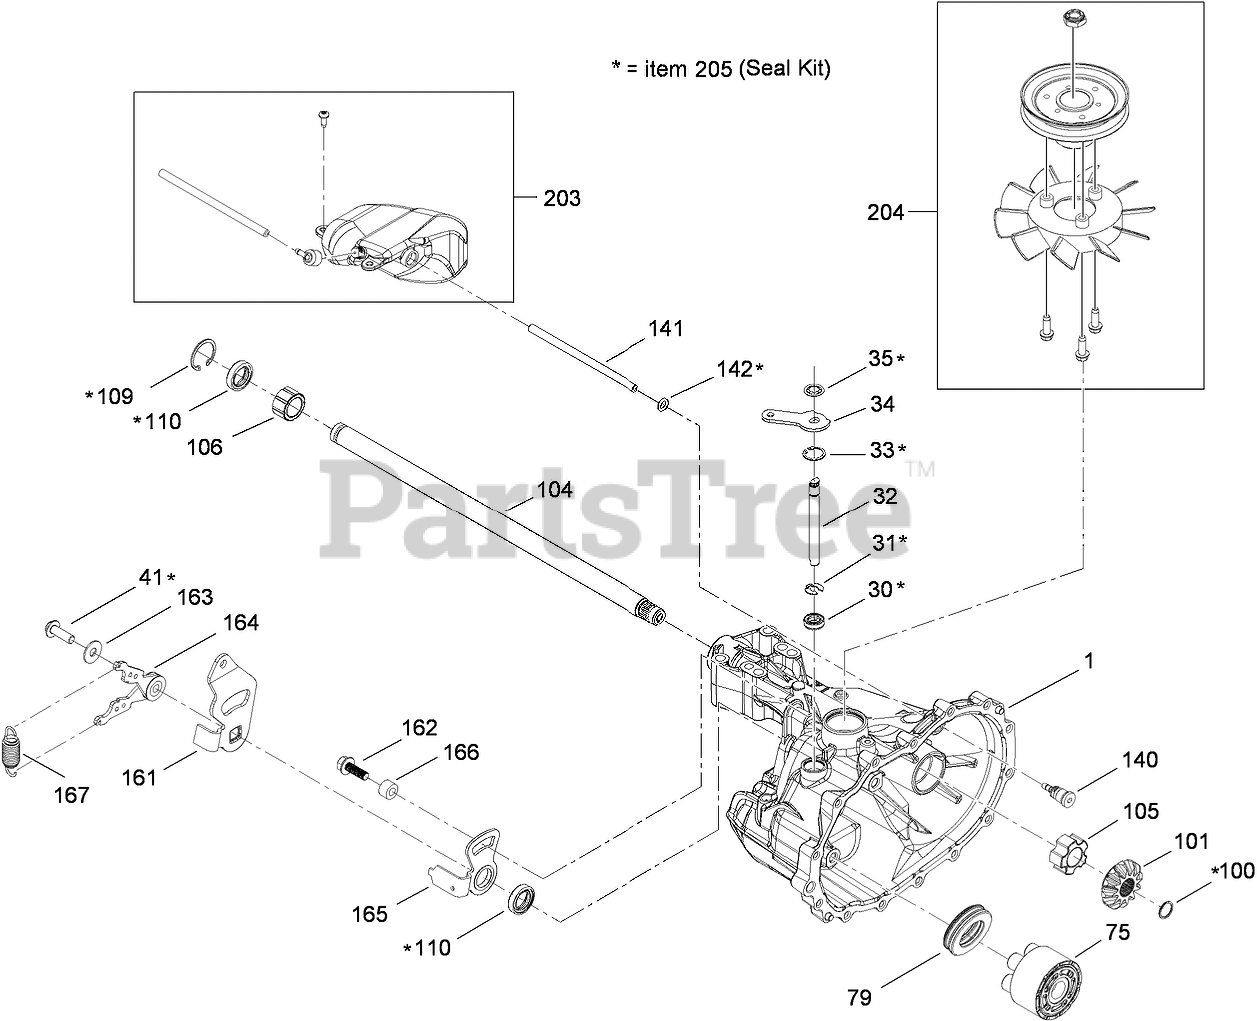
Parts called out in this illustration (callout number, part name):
1	MAIN HOUSING KIT
30	SEAL-LIP
31	RING-RETAINING, EXTERNAL
32	ROD-BYPASS, ACTUATOR
33	RING-RETAINING, INTERNAL
34	ARM-BYPASS
35	RING-RETAINING, EXTERNAL
75	CYLINDER BLOCK KIT
79	BEARING-THRUST
100	RING-RETAINING, SPIRAL
101	GEAR-BEVEL, 12T (SPLINE, ID)
104	SHAFT-AXLE, KEYED
105	BUSHING-INBOARD
106	BUSHING-OUTBOARD
109	RING-RETAINING, INTERNAL
110	SEAL
140	FITTING-SAE
142	O-RING
161	ARM-CONTROL, RETURN
162	SCREW-HF
163	WASHER
164	BI DIRECTIONAL RETURN KIT
165	ARM-NEUTRAL
166	BUSHING
167	SPRING-EXTENSION
203	EXPANSION TANK KIT
204	FAN AND PULLEY KIT
205	SEAL KIT
